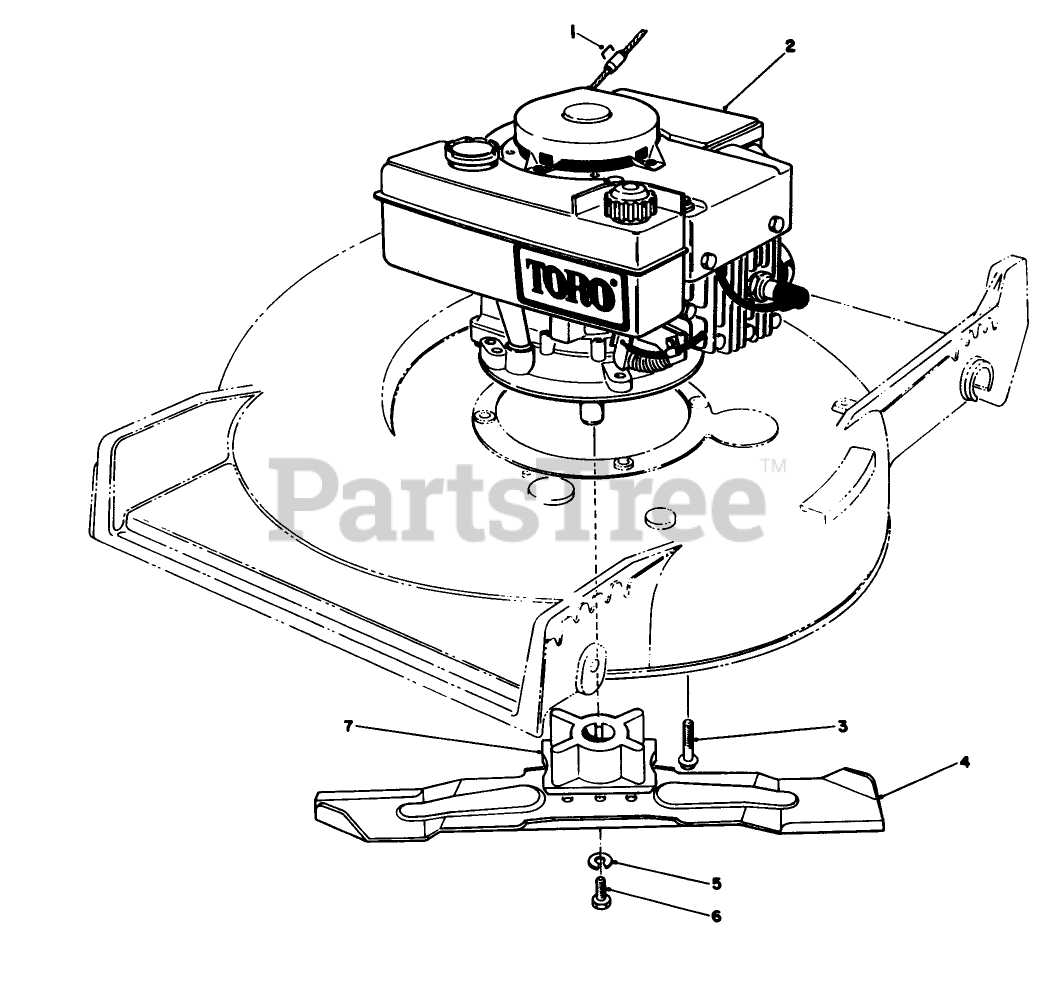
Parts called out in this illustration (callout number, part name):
1	Staple
2	Engine
3	3/8-16 X 2 CAPSCREW
5	WASHER-LOCK
6	SCREW-BLADE
7	BLADE RETAINER
